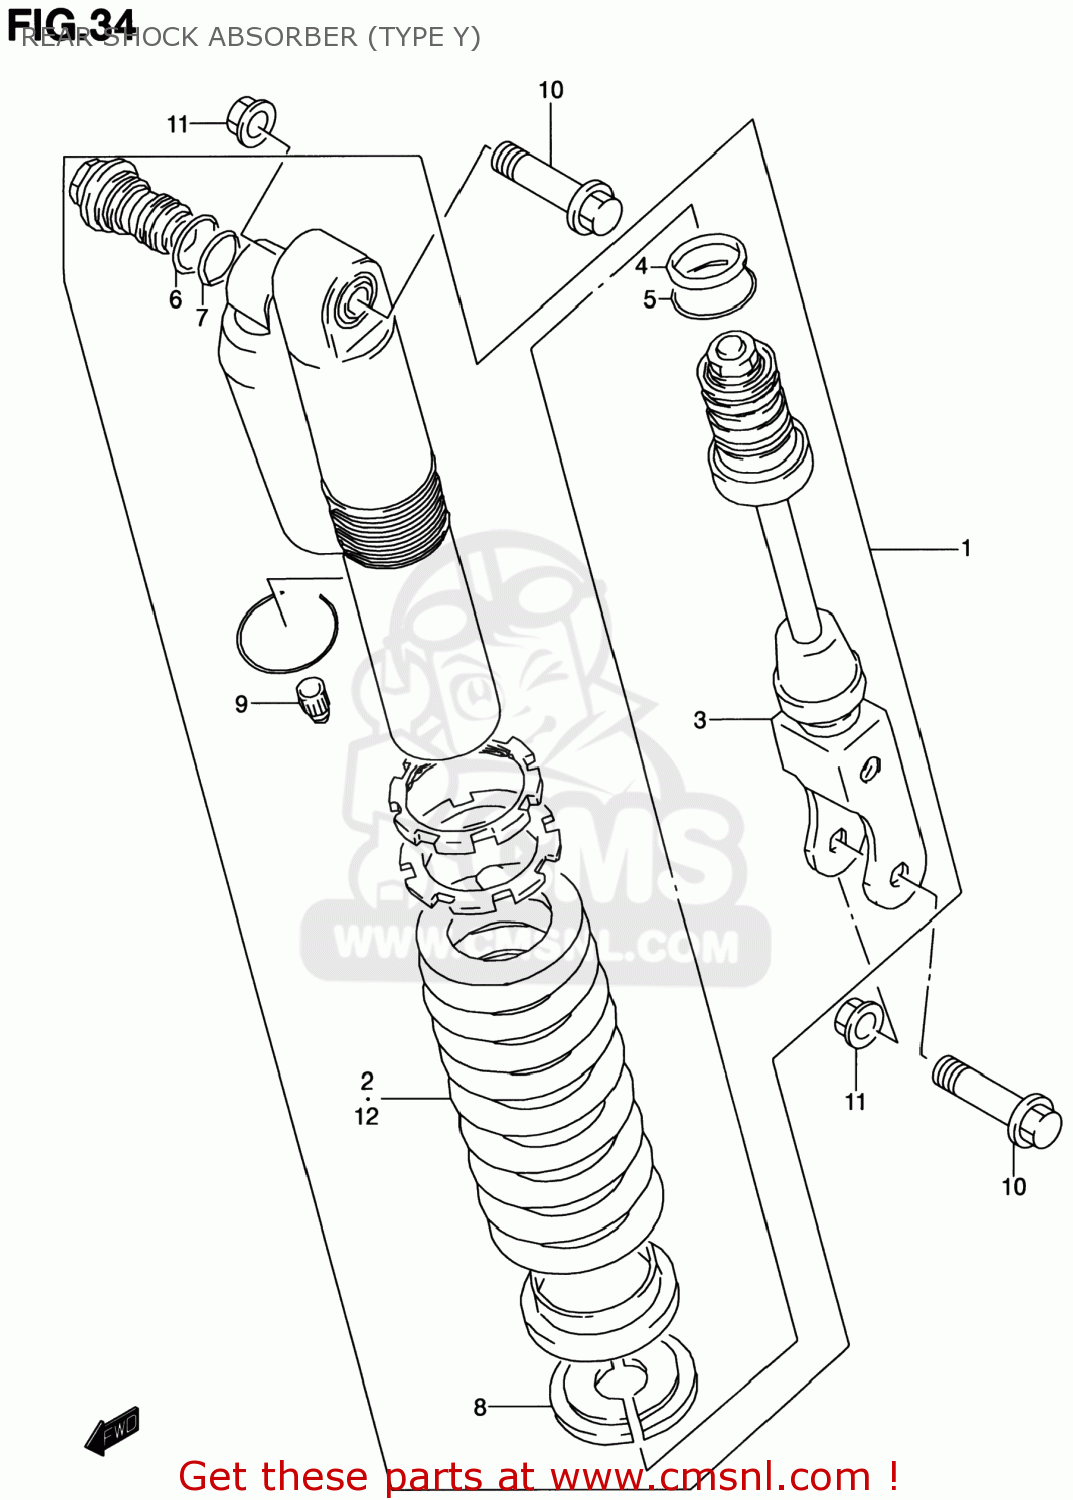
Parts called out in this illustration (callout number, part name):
1	ABSORBER ASSY.R
2	SPRING,REAR
3	ROD,PISTON
4	O RING
5	RING,PISTON ROD STOPPER
6	O RING
7	O-RING,FORK BOLT,LOWER
8	SEAT,SPRING STOPPER
9	CAP
10	BOLT,RR CUSHION ROD UPR
11	NUT
12	SPRING(SOFT)
